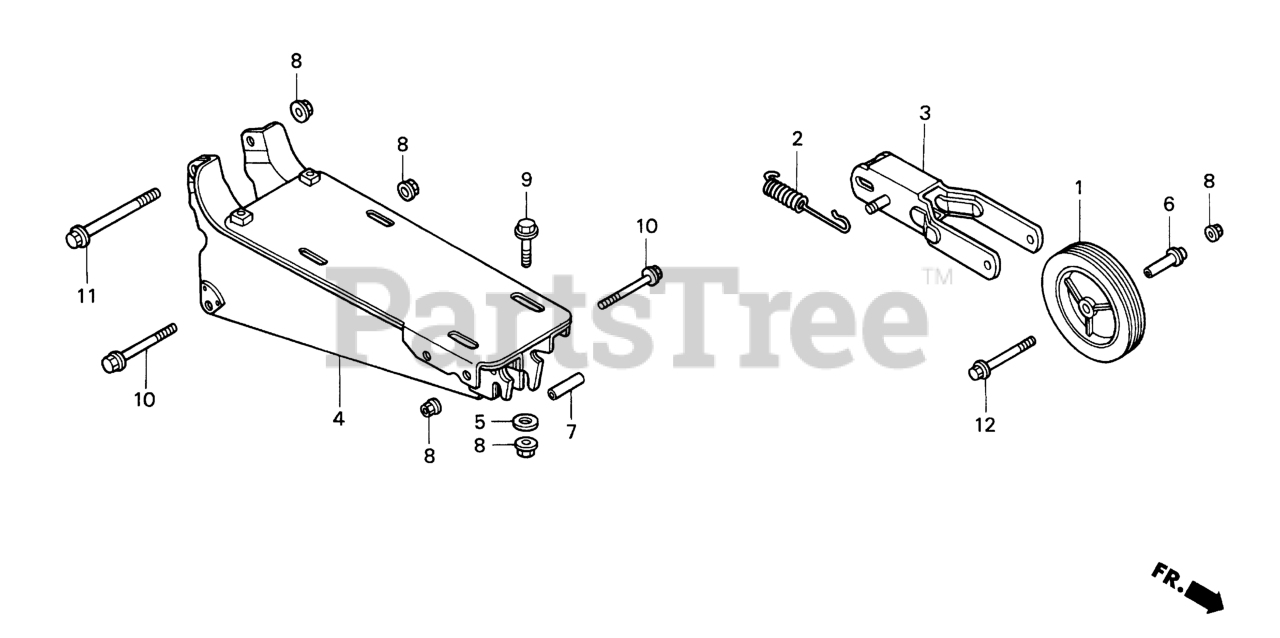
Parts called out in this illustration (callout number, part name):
1	WHEEL (7")
2	SPRING, RETURN
3	BEAM, FR. WHEEL
4	BED, ENGINE
5	WASHER (8X22)
6	COLLAR, FR. WHEEL
7	COLLAR, ENGINE BED
8	NUT, FLANGE (8MM)
9	BOLT, FLANGE (8X35)
10	BOLT, FLANGE (8X55)
11	BOLT, FLANGE (8X65)
12	BOLT, FLANGE (8X70)
